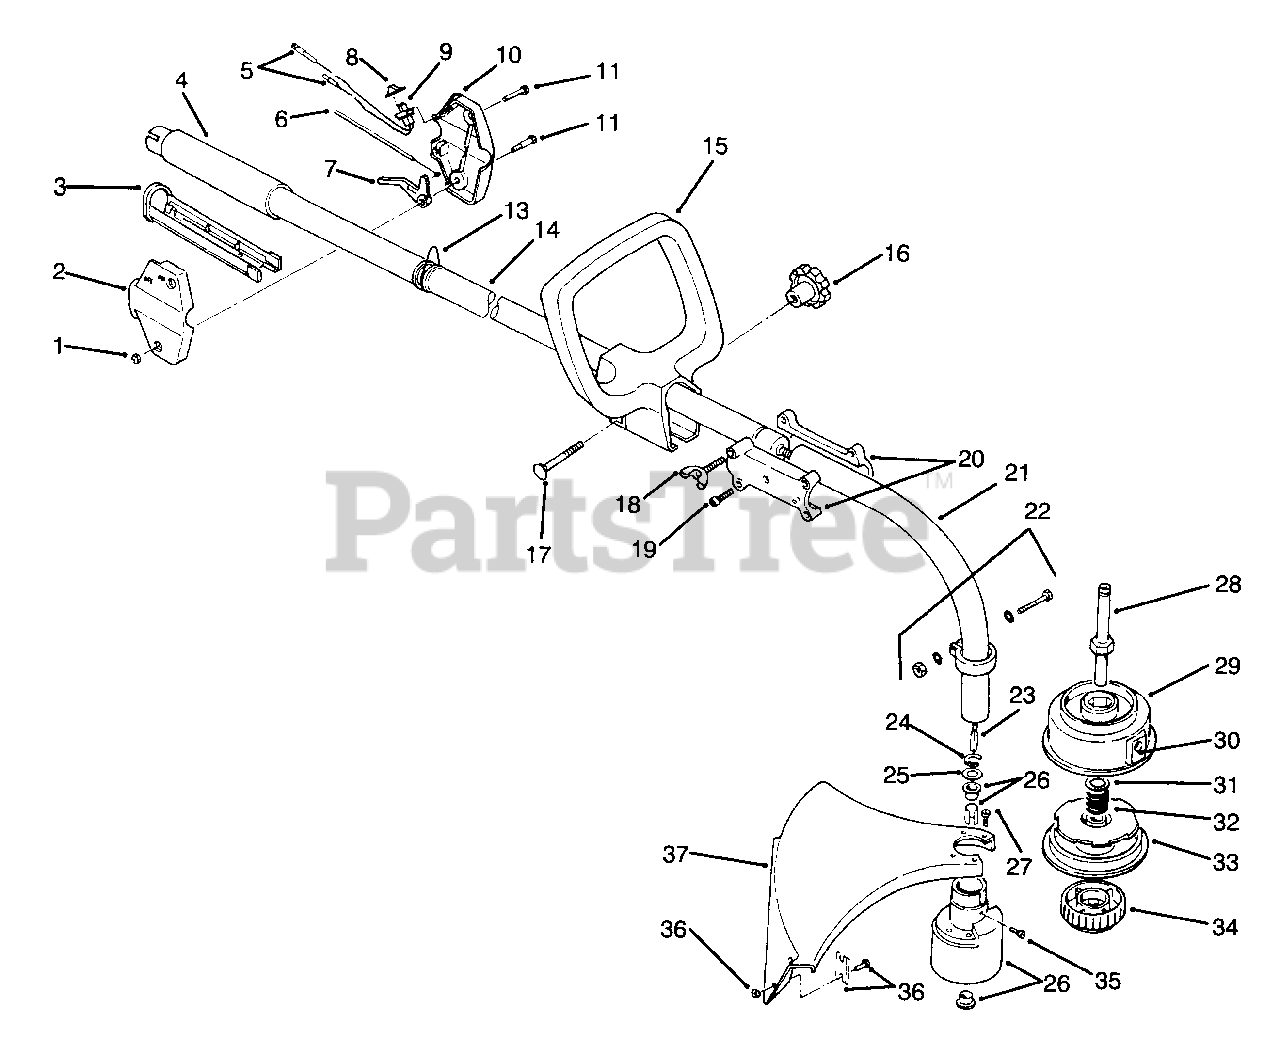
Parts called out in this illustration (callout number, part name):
1	Nut-Lock
2	Housing-R.H.
5	Assembly-Lead Wire
6	Cable-Throttle
7	Lever-Throttle
8	Cap-Switch
10	Housing-L.H.
11	Screw-Hex. Hd.
13	Clamp-Shoulder Strap
14	Assembly-Upper Drive
16	Knob-Loop Handle
17	Bolt-Carriage
18	Knob-Adjustment
19	Bolt Set-Coupling
20	Coupling Set-Split Boom
21	Assembly-Lower Drive
22	Assembly-Lower Clamp
23	Shaft-Flexible Drive
24	Ring-Retaining
26	Assy.-Bushing Housing
27	Assy. Guard Mounting Screw
28	Shaft-Spool
29	Assy.-Outer Spool & Eyelet
31	Retainer (10 Pack)
32	Reel-Inner
34	Assy.-Bump Head Knob
35	Screw-Anti-Rotation
36	Assy.-Blade (Incl. 2 Screws & 2 Nuts)
37	Assembly-Guard & Blade (Incl. Ref. No. 36)
